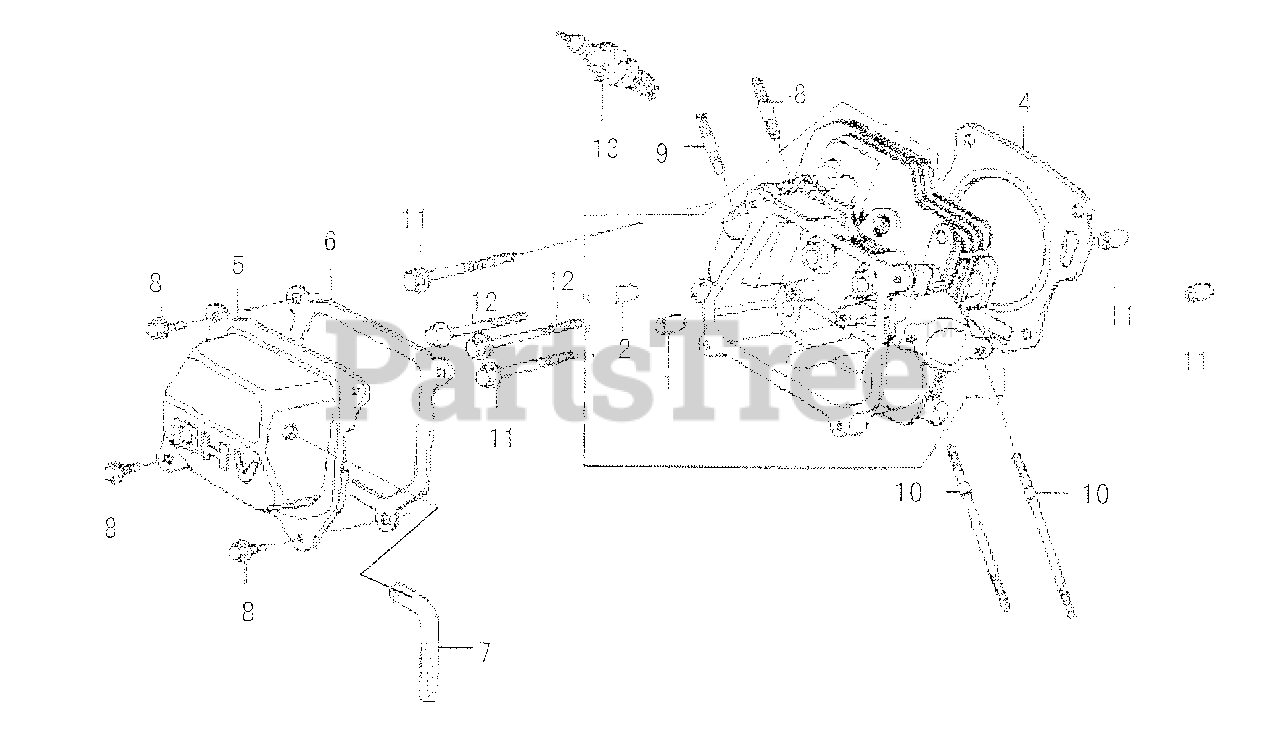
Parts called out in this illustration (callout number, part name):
1	GUIDE, INLET VALVE
2	GUIDE, EXH VALVE
4	GASKET, CYLINDER HEAD
5	COVER COMP, HEAD(BLACK)
6	GASKET, HEAD COVER
7	TUBE, BREATHER(ARC)
8	BOLT, FLANGE 6 X 12
9	BOLT, STUD 8 X 35
10	BOLT, STUD 6 X 90
11	DOWEL PIN, 10 X 16
12	BOLT, FLANGE 8 X 60
13	SPARK PLUG F6TC
